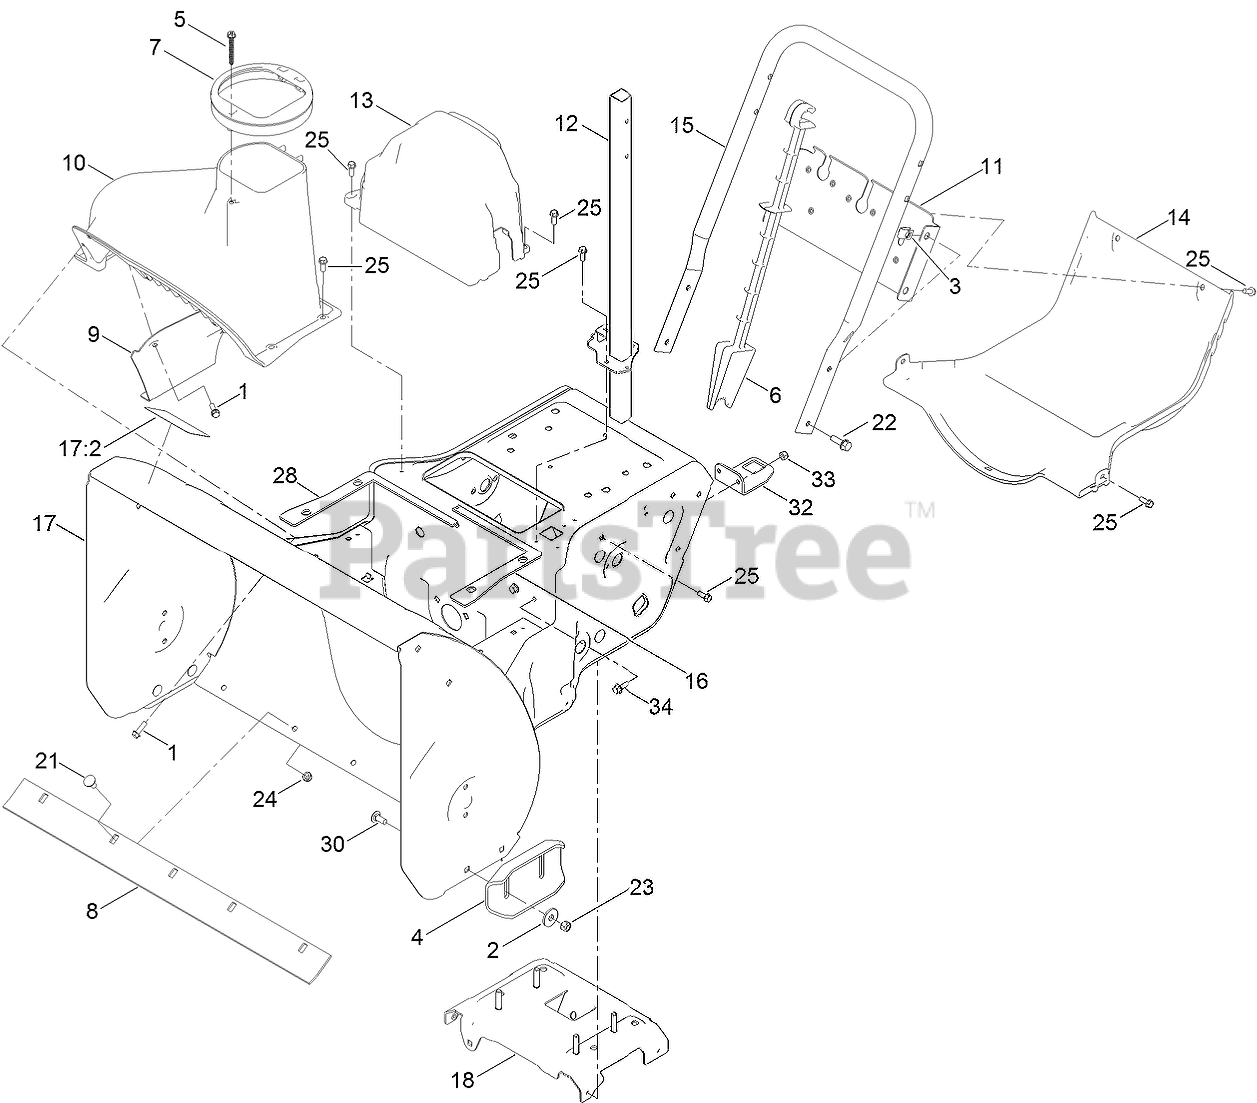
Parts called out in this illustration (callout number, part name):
1	SCREW-PLASTITE, HWH
2	WASHER-FLAT
3	NUT-U
5	SCREW-HWH, PLASTITE
6	STICK-CLEANOUT
7	GUIDE-CHUTE
8	SCRAPER-24 INCH
9	COVER-LINER
11	BRACE-FRAME
12	SUPPORT-CHUTE
13	COVER-BELT
14	COVER-LOWER
15	HANDLE-LOWER
16	SEAL-HOUSING, LH
17	FRAME ASM
17:2	DECAL-DANGER, AUGER
18	BRACE-FRAME
21	BOLT-CARR
22	SCREW-HHF
23	NUT-HEX
24	NUT-HEX
25	SCREW-HWH
28	SEAL-HOUSING, RH
30	BOLT-CARR
32	BRACKET-POST, CHUTE
33	SCREW-HHF
34	NUT-HEX
